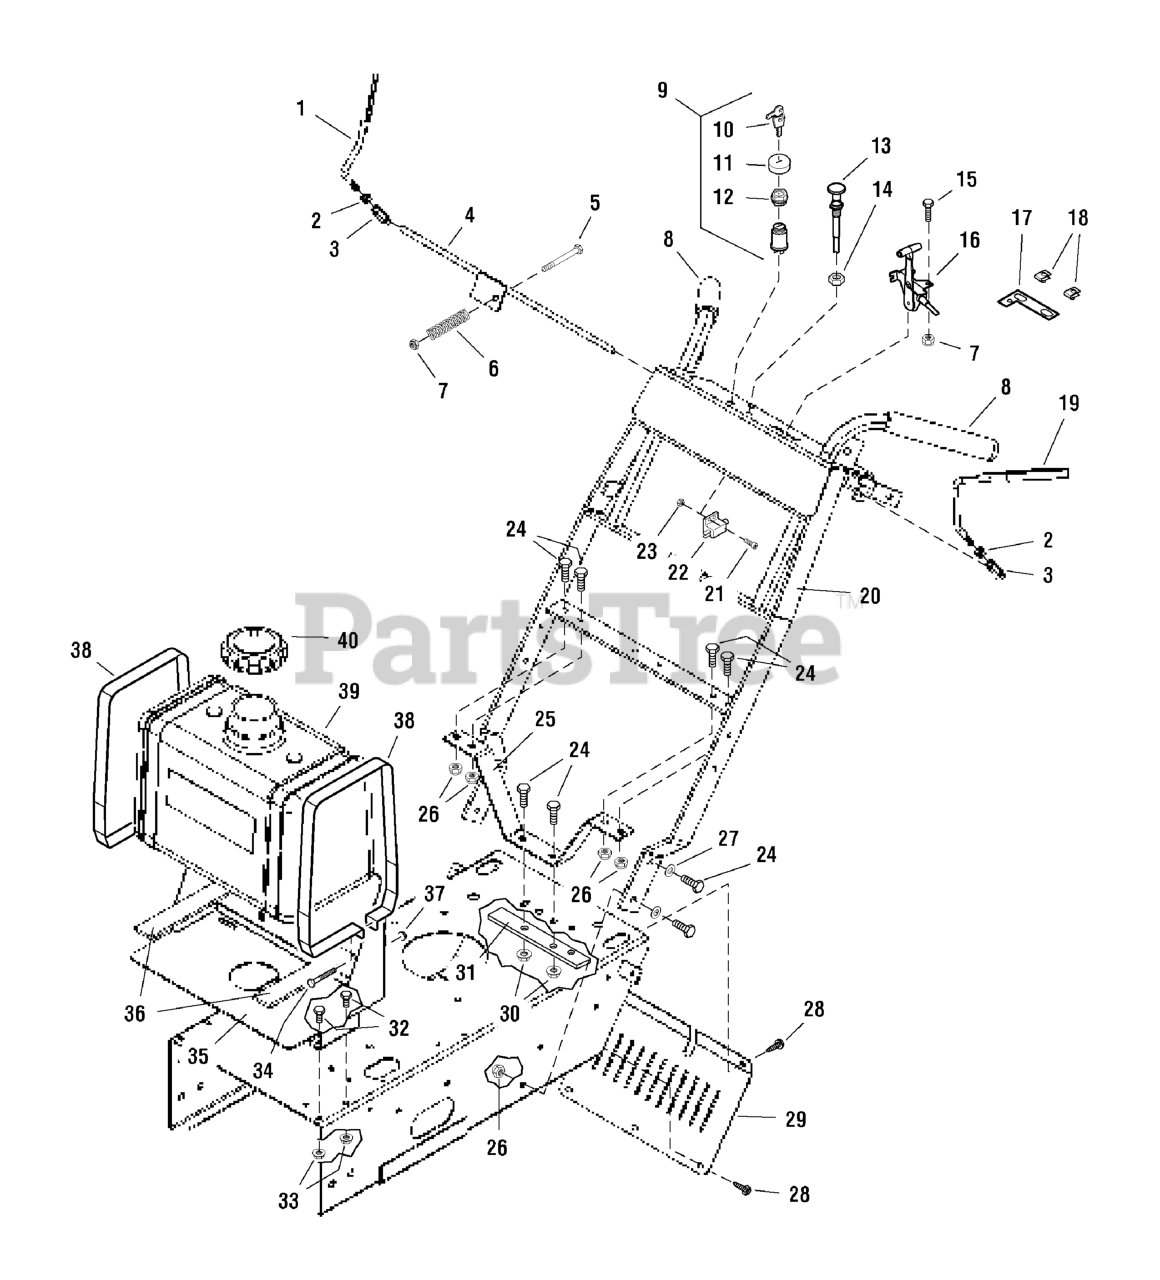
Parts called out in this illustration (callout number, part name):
1	ASSM, OPERATOR PRESENCE, RH
1	GRIP, Vinyl
2	NUT, 3/8-16 Hex
3	HEX ADJUSTER
4	SWITCH ROD
5	BOLT, 1/4-20 x 3
6	SPRING, Compression
7	NUT, 1/4-20 HEX NYLON LOCK
8	GRIP, Foam
9	SWITCH, Ignition, Complete
10	KEY, IGNITION MOLDED SET
11	COVER, PLASTIC, SNAP ON
12	PLASTIC NUT
13	CABLE, Choke Control, 47"
14	NUT, 3/8-24 Hex
15	BOLT, 1/4-20 x 3/4
16	CABLE, Throttle, 45"
17	PLATE, THROTTLE STOP
18	BODY CLIP, 1/4-20
19	ASSM, OPERATOR PRESENCE, LH
19	GRIP, Vinyl
20	HANDLE BAR ASSEMBLY
21	SCREW, #10-24 x 1/2
22	SWITCH, PLUNGER, N.C.
23	NUT, #10-24 Hex
24	BOLT, 3/8-16 X 1" GD5 CZ
25	HANDLE BAR SUPPORT
26	NUT, 3/8-16 HEX NYLON LOCK
27	WASHER, 3/8 SAE
28	BOLT, Self-Tapping, 1/4-20 x 3/4
30	NUT, 3/8-16 Hex Serrated Flange
31	ENGINE DECK SUPPORT
32	BOLT, 5/16-18 X 3/4 GD5
33	NUT, 5/16-18 HEX SERRATED FLANGE (SMALL)
34	BOLT, 1/4-20 X 1-1/2
35	FUEL TANK MOUNT
36	RUBBER PAD
37	NUT, 1/4-20 HEX SERR. FLANGE
38	FUEL TANK STRAP
39	TANK, FUEL, PLASTIC, 5 GALLON W/ FUEL LINE
40	CAP, GASOLINE, VENTED
